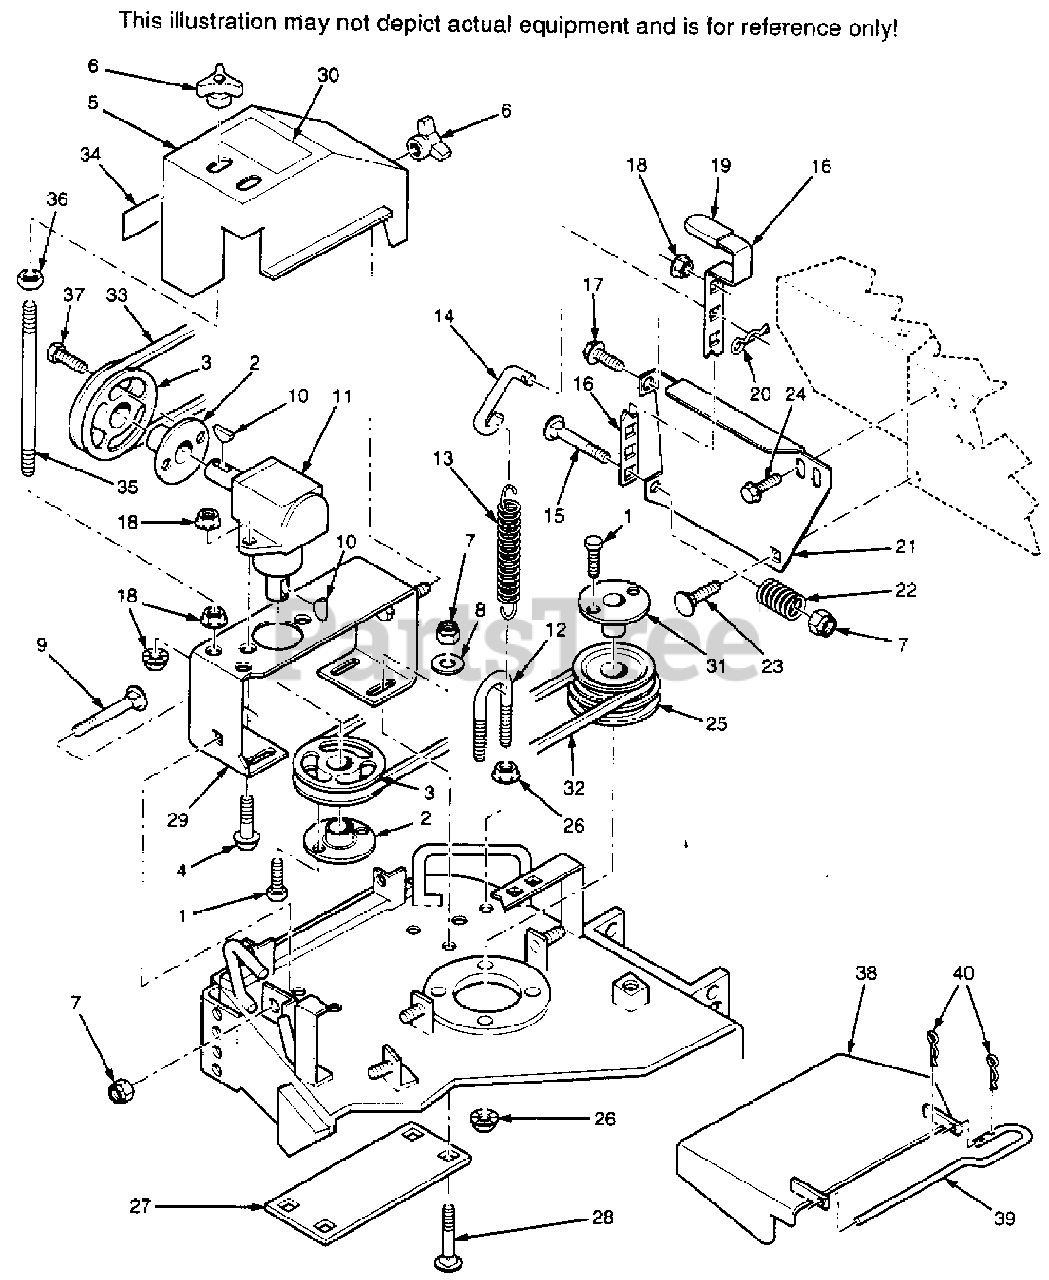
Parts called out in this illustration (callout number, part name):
1	BOLT, HEX HEAD 1/4-20 X .75
2	TAPERED HUB, .875 BORE
3	PULLEY, TAPERED BORE 5.80 O.D.
4	CAPSCREW, SERR. FLANGE 3/8-16 X 1.25
5	BELT COVER, W/DECALS
6	WINGNUT, PLASTIC 3/8-16 X .875
7	NUT, ELASTIC STOP 3/8-16
8	FLAT WASHER, 3/8(.375 X 2.00 X .060)
9	CARRIAGE BOLT, 3/8-16 X 2.00
10	KEY, WOODRUFF #9 3/16 X .75
11	GEAR BOX, 90 DEGREE DRIVE
12	U-BOLT, 5/16-18 X 2.19
13	SPRING, CLUTCH
14	ROD, COUNTER BALANCE
15	CARRIAGE BOLT, 3/8-16 X 2.00
16	LEVER, COUNTER BALANCE
17	CAPSCREW, SERR. FLANGE 3/8-16 X .75
18	NUT, SERR. FLANGE 3/8-16
19	GRIP, SHIFT LEVER
20	HAIR PIN, .094 X 1.62
21	MOUNTING BRACKET, COUNTER BALANCE
22	SPRING, COMPRESSION
23	CARRIAGE BOLT, 5/16-18 X 1.00
24	CAPSCREW, 5/16-18 X .75
25	PULLEY, TAPERED BORE 5.15 O.D.
26	NUT, SERR. FLANGE 5/16-18
27	REINFORCEMENT PLATE, GEAR BOX
28	CARRIAGE BOLT, 3/8-16 X 1.25
29	SUPPORT WELDMENT, GEAR BOX
30	DECAL, WARNING
31	TAPERED HUB, 1.00 BORE
32	BELT, GEAR BOX DRIVE
33	BELT, BLOWER DRIVE
34	DECAL, WARNING
35	STUD, 3/8-16 X 6.75
36	NUT, CENTER LOCK 3/8-16
37	BOLT, HEX HEAD 1/4-20 X 1.25
38	DISCHARGE CHUTE
39	ROD, DISCHARGE CHUTE
40	HAIR PIN, .080 X 1.19
